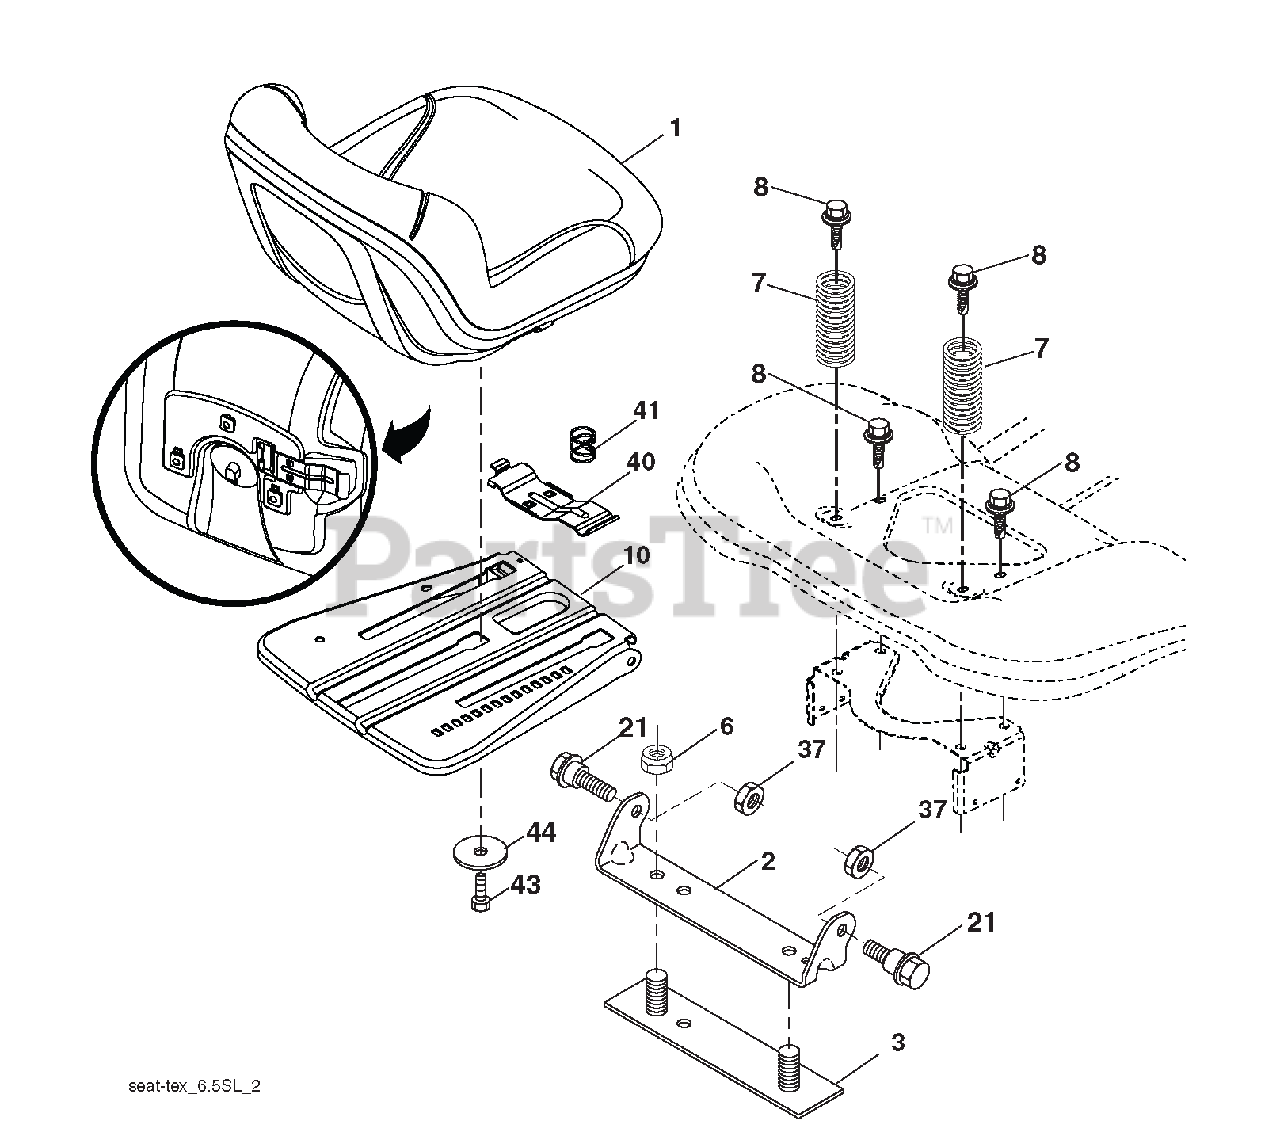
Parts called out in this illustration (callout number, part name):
1	SEAT.TA150.KB/SLD.BLK.ARIENS
2	BRACKET.PIVOT.FENDER.2002
3	STRAP ASM.FENDER.94
6	Locknut, Washer Insert 3/8-16
7	SPRING.SEAT.CPRSN.2.250.BLK.ZI
8	BOLT.5/16-18UNCX3/4 W/SEMS.BLK
10	PAN ASM.SEAT.3PT.
21	BOLT.SHLD.5/16-18 UNC-2A.BLK D
37	Locknut, Washer Insert 5/16-18
40	HANDLE.SLIDE.SEAT.TEX.MILSCO
41	SPRING.LATCH.SEAT.TEX
43	BOLT.FIN.HEX.3/8-16UNC X 3/4
44	WASHER.13/32 X 2 3/8 X 12GA.
